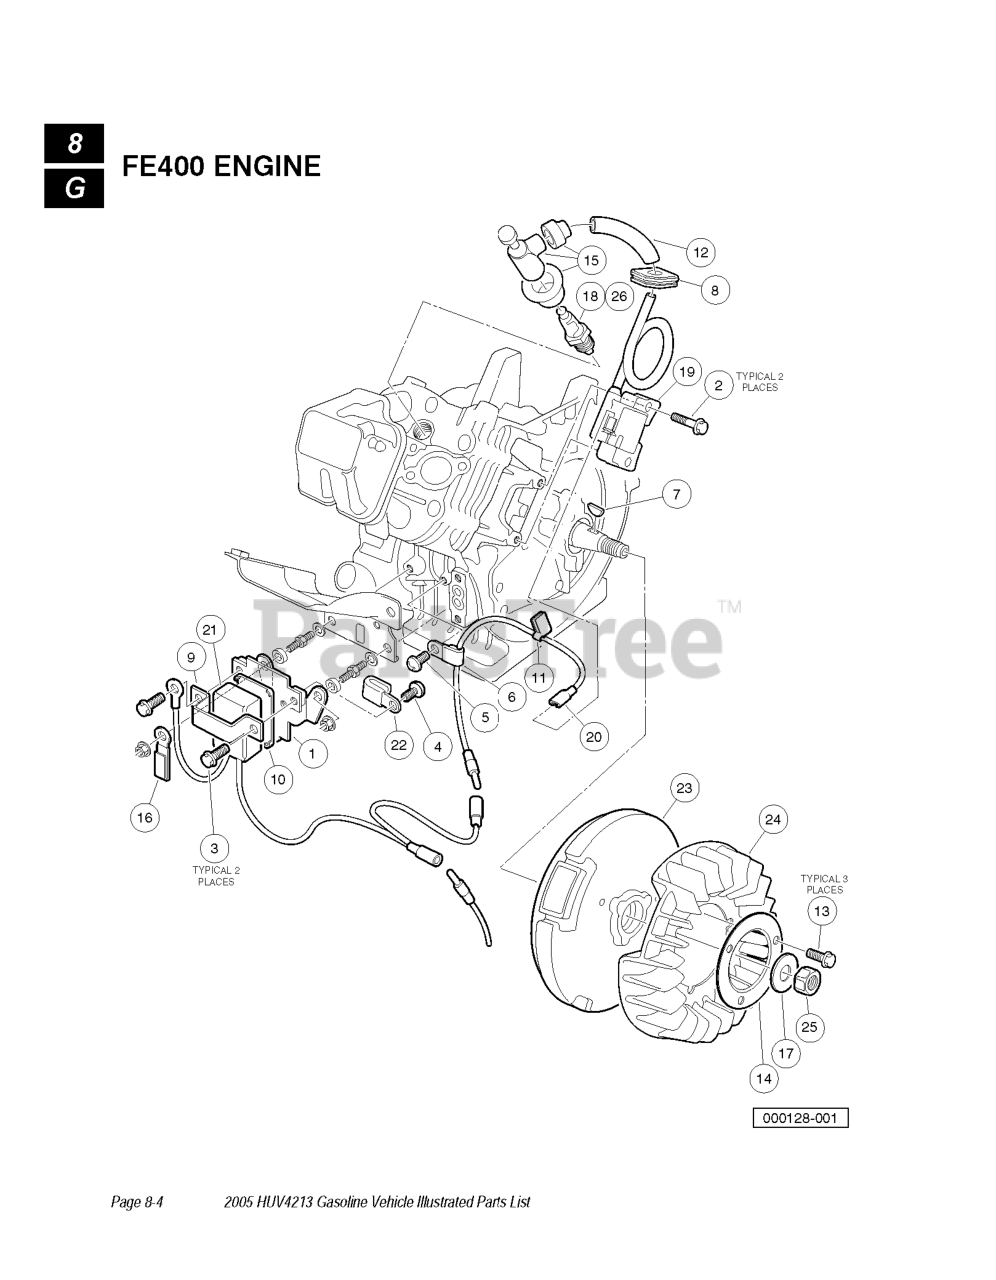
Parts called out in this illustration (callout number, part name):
1	BRACKET, RPM LIMITER
2	BOLT, FLANGED
3	BOLT, FLANGED
4	SCREW, PAN WP CROSS
9	BAND, RPM LIMITER MOUNT
10	DAMPER, RPM LIMITER
12	TUBE, 7MM X 10MM X 70MM
13	BOLT - FLANGED
15	CAP ASM PLUG
17	WASHER, FLAT
18	SPARK PLUG OHV
19	COIL, IGNITION
20	LEAD WIRE ASSY
21	LIMITER, RPM
23	FLYWHEEL COMPLETE, FE350
24	FAN, FE350 CW
25	Nut, Fine Hex, 18mm
26	NGK OHV SPARK PLUG
